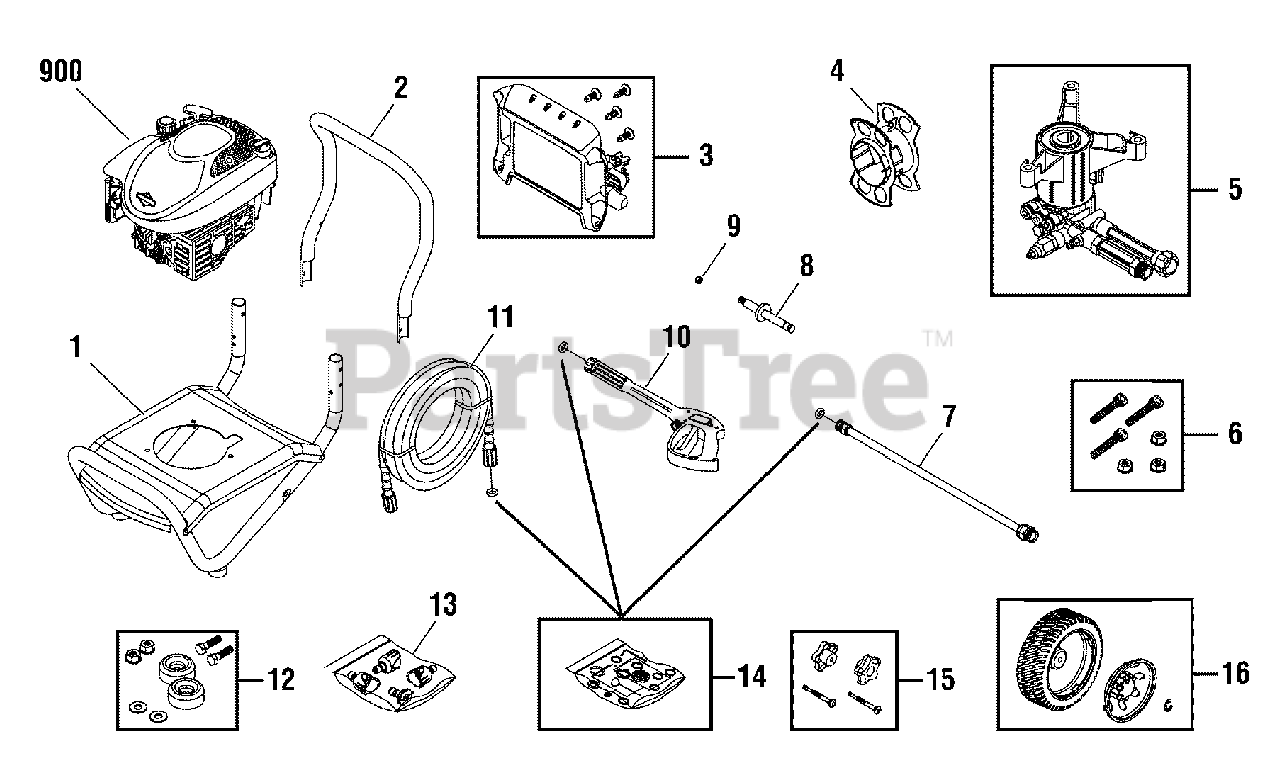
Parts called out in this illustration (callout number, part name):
6	KIT, Hardware, Pump Mounting
7	EXTENSION, QC
9	NUT
10	GUN
11	HOSE
12	MOUNT, Vibration
13	KIT, QC Nozzles
15	KIT, Hardware, Handle
900	* ENGINE
